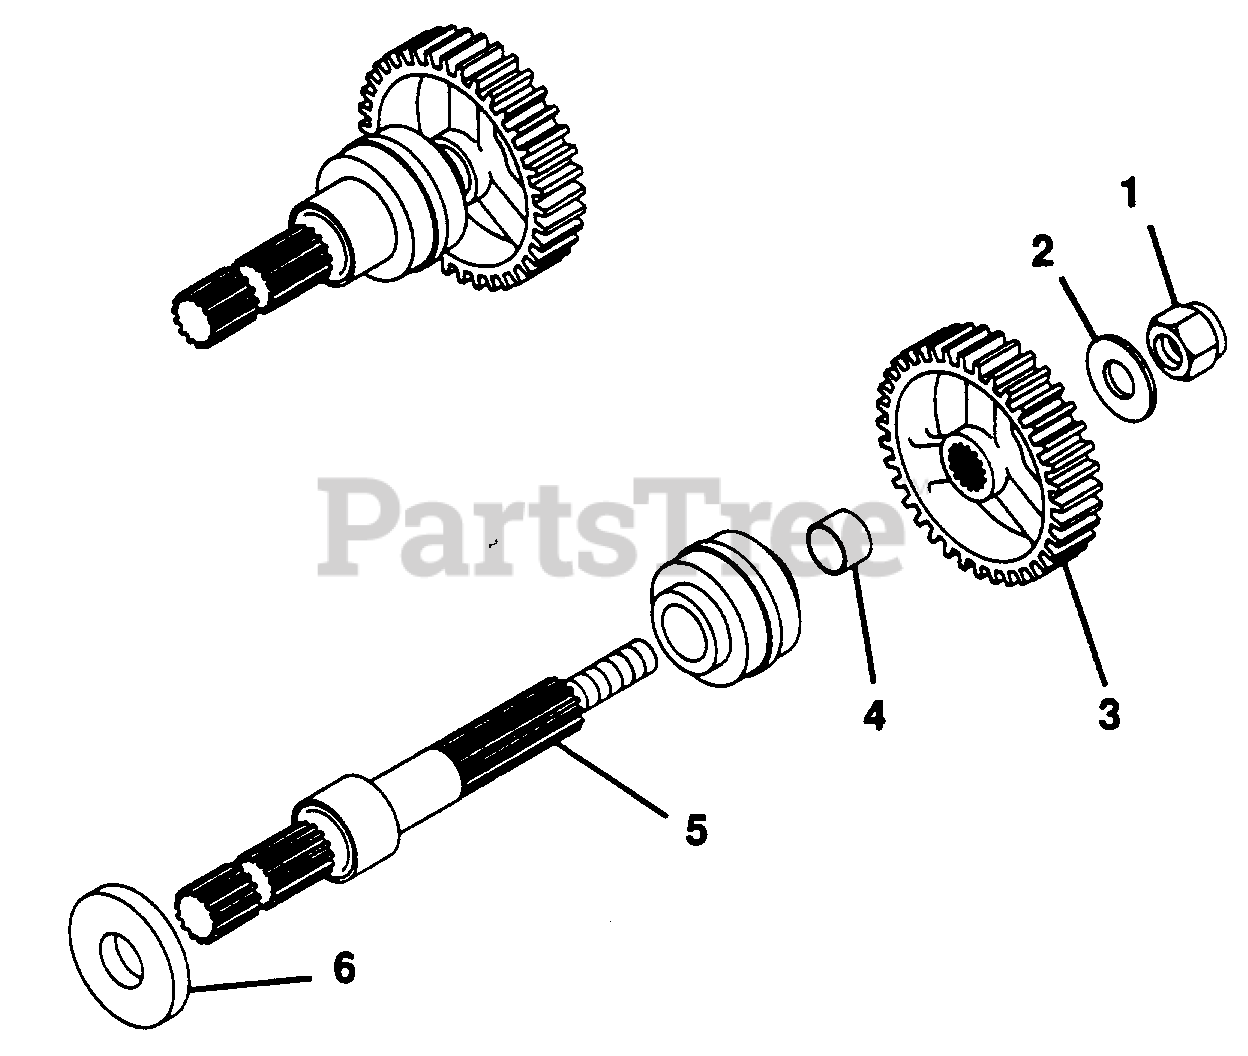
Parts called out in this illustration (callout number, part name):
1	NUT, LOCK 5/8-11
2	WASHER, FLAT .687X1.312X.122
3	GEAR, SPUR PTO 10 DP 56 T X .75
4	SPACER, 1.060X1.375X.450
5	SHAFT, PTO
6	SEAL, OIL 1.375X2.129X.312
